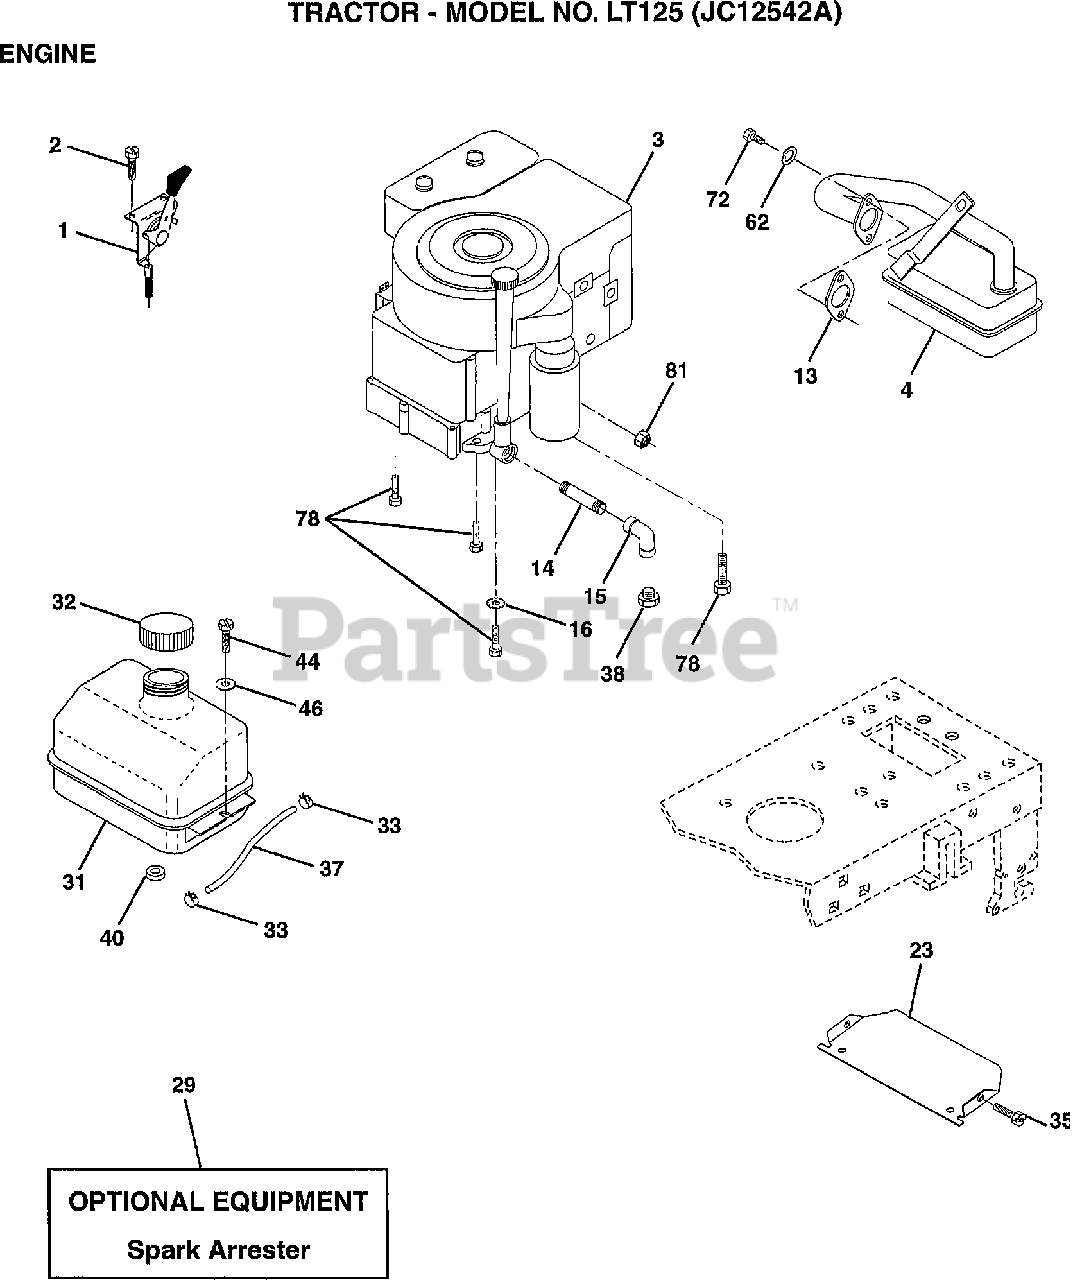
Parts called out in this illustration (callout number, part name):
2	SCREW HEX THD CUT 1/4-20X5/8 T
14	NIPPLE PIPE 3/8 NPT X 3"
15	ELBOW STD 90 DEGREE 3/8-18 NPT
16	WASHER LOCK
29	KIT.ARREST.SPARK (392-390)
35	SCREW THDROL 5/16-18 X 3/4 TYT
44	SCREW HEXWSH THDROL 1/4-20X3/4
46	WASHER 9/32 X 7/8 X 16 GA
72	SCREW HEXHD CAP 5/16-18X3/4
78	SCREW THDROL 3/8-16 X 1-1/4 TYTT
